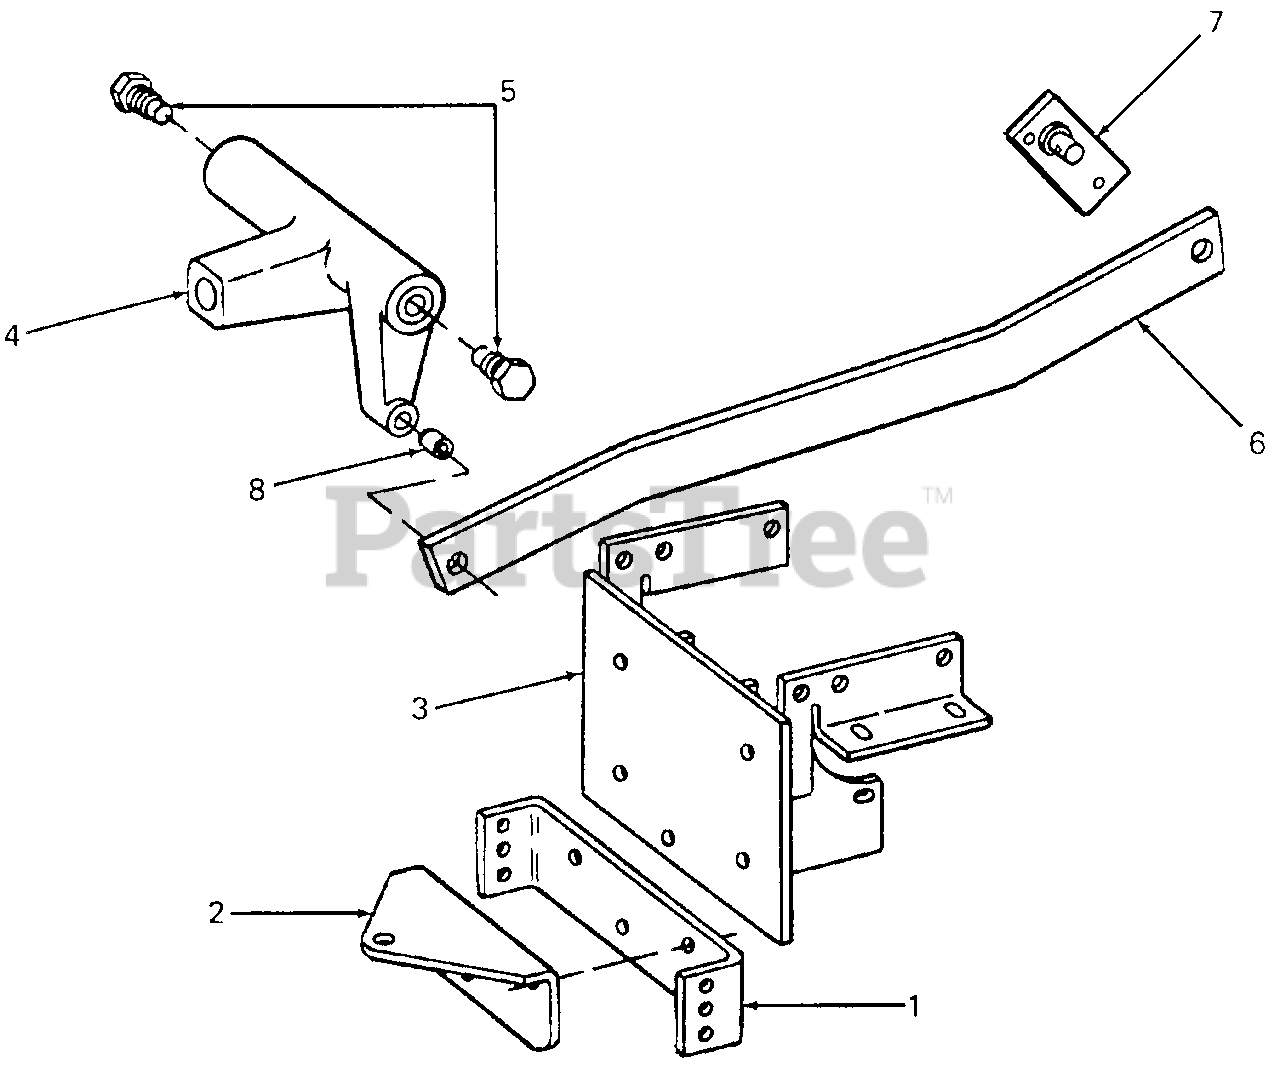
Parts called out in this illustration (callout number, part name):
3	Bracket Assy, Hitch
4	Lever, Lift
5	Bolt, Stub Shaft
6	Bar, Lift
7	Plate Assy, Lift Bar
8	Spacer, Lift Arm
